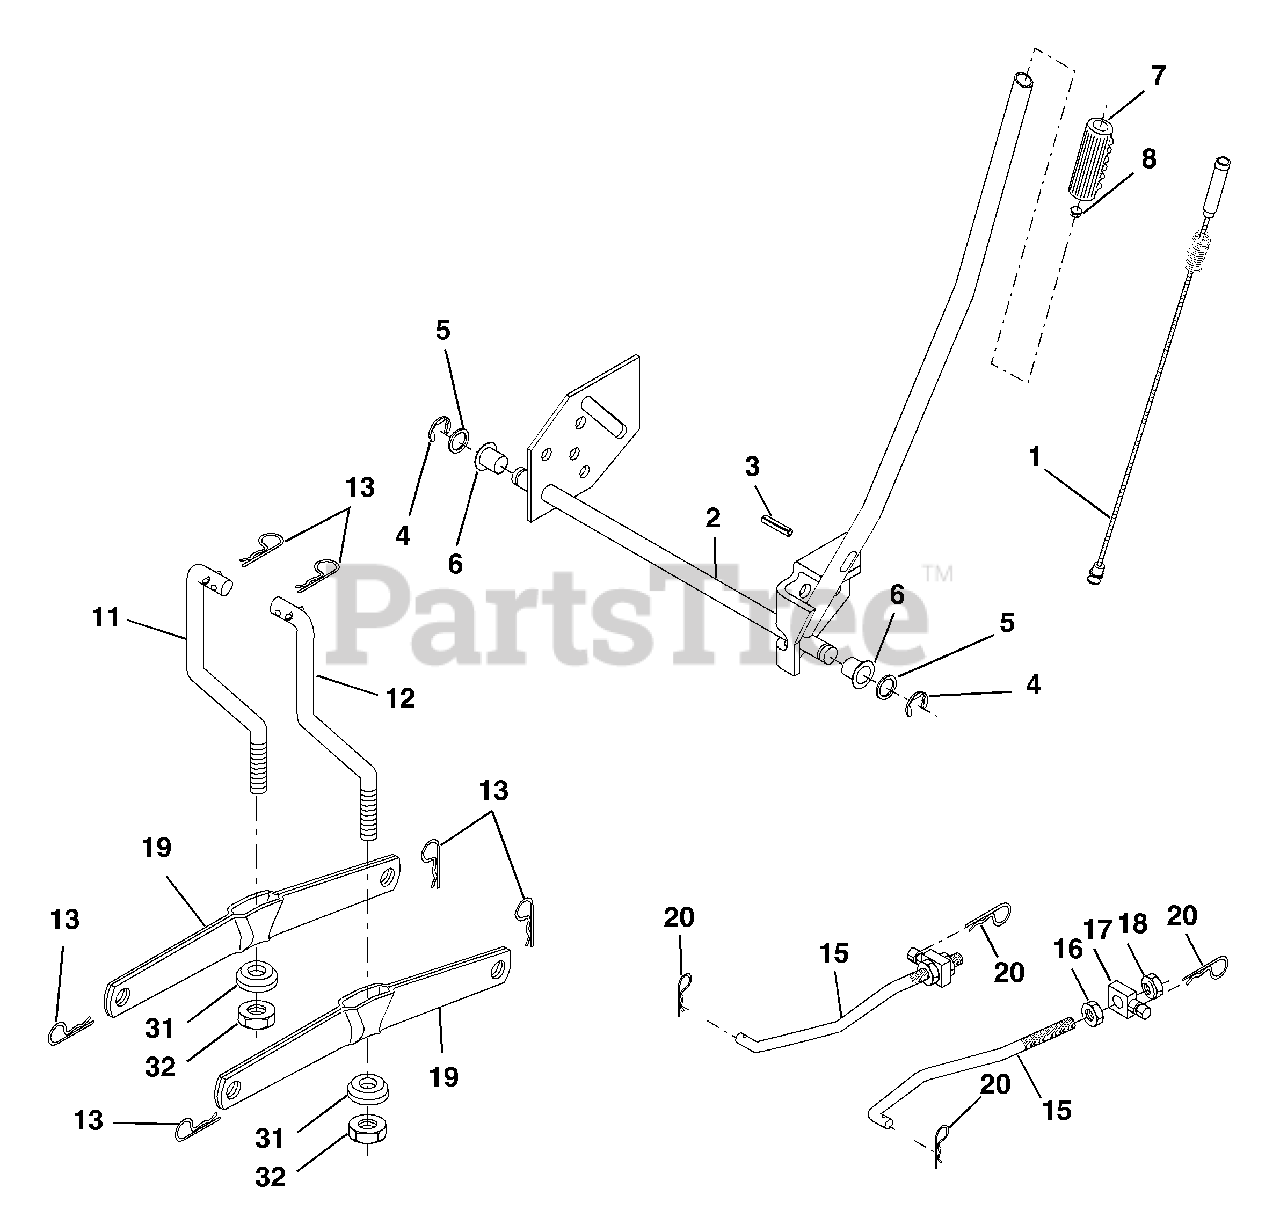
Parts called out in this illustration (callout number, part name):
1	Wire Asm Inner Sprg w/Plunger LT
2	Shaft Asm Lift
3	Pin Groove
4	E Ring #5133-62
5	Washer PLTD 21/32 X 1 X 21ga
6	Bearing Nylon Blk 629 Id
7	Grip Handle Fluted
8	Button Plunger Black
11	Link Lift LH
12	Link Lift RH
13	Retainer Spring
15	Link Front
16	Nut Jam Hex 1/2-13 Unc
17	Trunnion Blk Zinc
18	Nut Lock w/wsh 1/2-13 Unc
19	Arm Suspension Rear
20	Spring, Retainer
31	Bearing Pvt. Lift
32	Nut Crownlock 3/8-24
